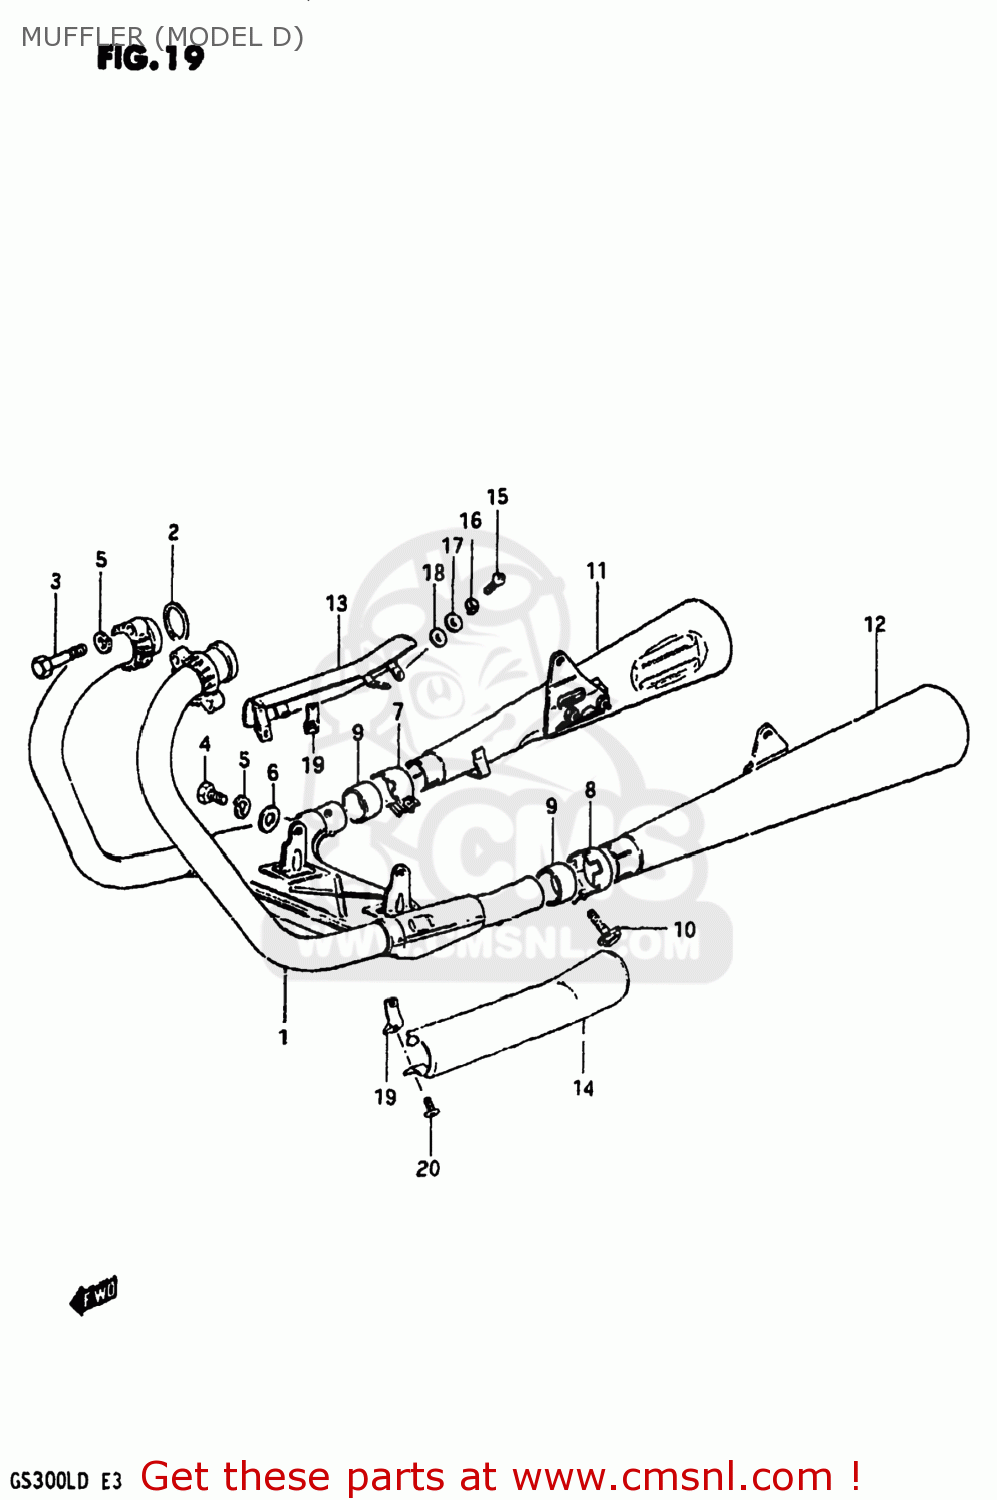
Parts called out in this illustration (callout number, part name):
1	PIPE,EXHAUST
2	GASKET,EXHAUST PIPE (NAS)
3	BOLT 8X40
4	BOLT
5	LOCK WASHER
6	WASHER
7	CLAMP,MUFFLER CONNECTOR,R
8	CLAMP,MUFFLER CONNECTOR,L
9	CONNECTOR,MUFFLER
10	BOLT
11	MUFFLER ASSY,R
12	MUFFLER ASSY,L
13	COVER,MUFFLER,RIGHT
14	COVER,MUFFLER
15	SCREW 6X12
16	LOCK WASHER
17	WASHER
18	GASKET 6.2X12X1.5 (MCA)
19	CLAMP,MUFFLER COVER
20	SCREW
